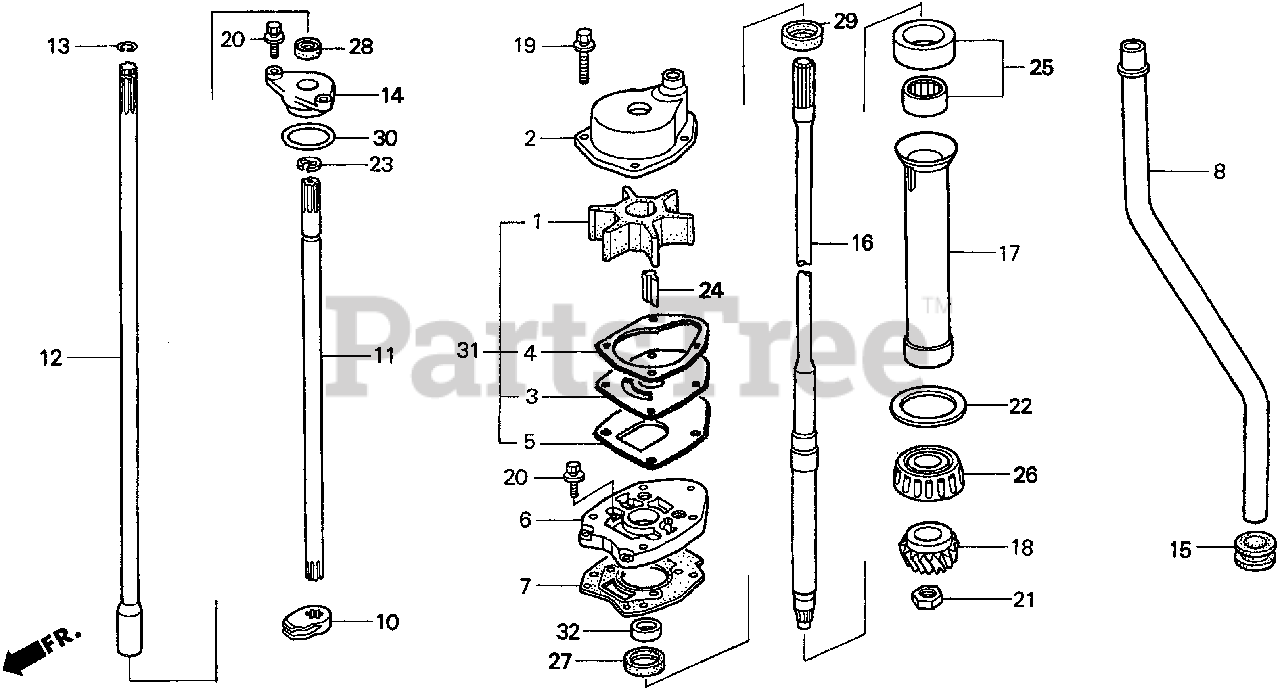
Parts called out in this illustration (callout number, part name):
1	IMPELLER, PUMP
2	HOUSING, IMPELLER
3	COVER, IMPELLER
4	GASKET, IMPELLER
5	GASKET B, IMPELLER
6	HOUSING, WATER PUMP
7	GASKET, WATER PUMP
8	TUBE, WATER (L)
10	CAM, SHIFT
11	ROD B, SHIFT (L)
12	ROD A, SHIFT
13	RING, STOPPER
14	HOLDER, SEAL
15	GROMMET, EXTENSION CASE
16	SHAFT, VERTICAL (L)
17	SLINGER, OIL
18	GEAR, PINION
19	BOLT, HEX.
20	BOLT, HEX.
22	SHIM, GEAR
24	KEY, SPECIAL
25	BEARING ASSY.
26	BEARING, TAPERED
27	SEAL, WATER (UPPER)
28	SEAL, WATER
29	SEAL, WATER (LOWER)
31	PUMP KIT, IMPELLER
32	SLEEVE ASSY., WEAR
